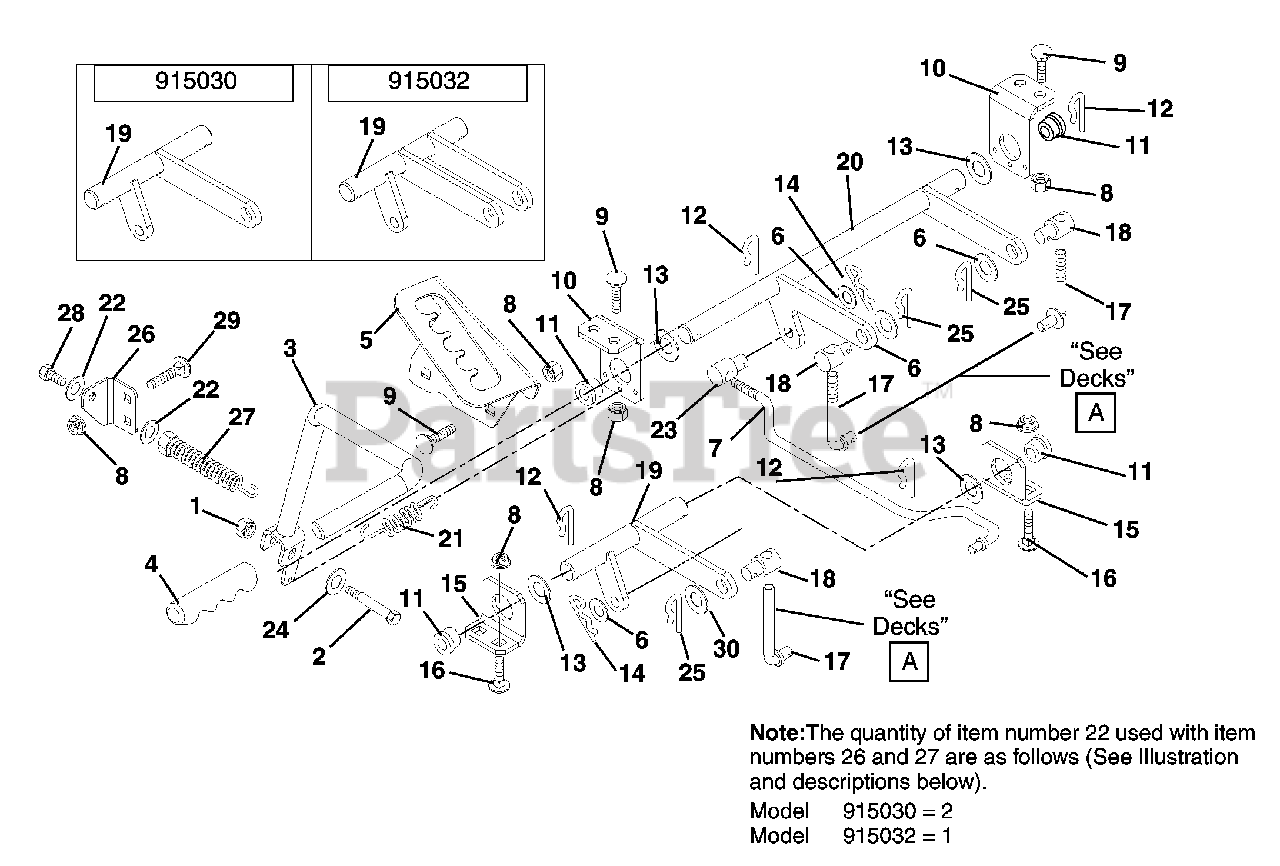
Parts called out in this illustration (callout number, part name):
1	Nut, Locking Top Flange .31-18
2	Bolt, 1.25 Socket Shoulder Plain
3	Weldment, Lift Handle
5	Detent Plate
6	Washer, Flat Steel .511 x 1.44 x .125
7	Rod, Deck Lift
8	Nut, Locking Top Flange .38-16
9	Bolt, Round Head Square Neck .38-16 x .75 Grade 5
10	Bracket, Lift
11	Bushing, Flange .75 x 1.00 x .625 x 1.25
12	Pin, Spring Clip
13	Washer-Flat-Steel .812 x 1.50 x .135
14	Pin, Hair #16
15	Bracket, Deck Pivot
16	Bolt, Round Head Square Neck .38-16 x 1.00 Grade 5
17	Rod, Link (030)
17	Rod, Link (032)
18	Trunnion (030)
18	Trunnion (032)
19	Weldment, Front Lift (030)
19	Weldment, Front Lift (032)
20	Weldment, Lift
21	Spring, Extension
22	Washer, Flat Steel .43 x 1.00 x .16 (030)
22	Washer, Flat Steel .43 x 1.00 x .16 (032)
23	Pivot, Rod
24	Washer, Flat Steel .43 x 1.00 x .160
25	Clip, Spring
26	Bracket, Spring Anchor
27	Spring, Tension .195 x 1.15 x 5.50
28	Bolt-Hex .38-16 x 1.50 Grade 5
29	Bolt-Round Head Square Neck .38-16 x 1.25
30	Washer, Flat Steel .563 x 1.38 x .109
